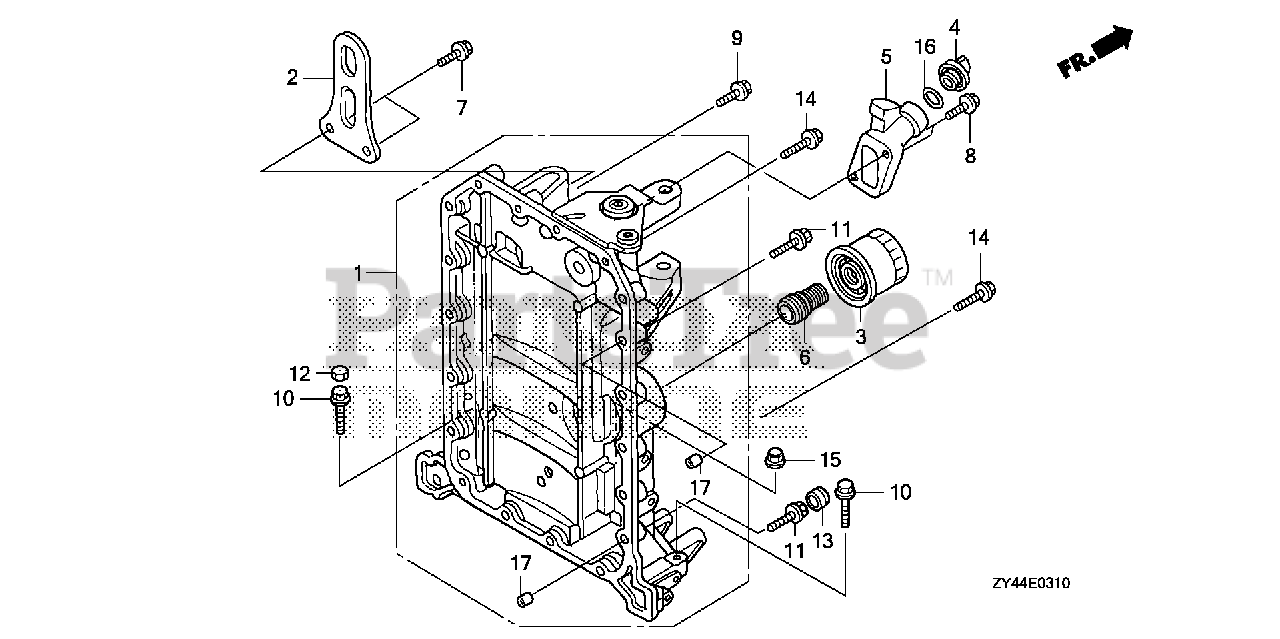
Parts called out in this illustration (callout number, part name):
1	CRANKCASE
2	HANGER, ENGINE
3	FILTER, OIL (FILTECH TOYO ROKI) (SOLD IN MULTIPLES OF 30)
3	FILTER, OIL (FILTECH TOYO ROKI) (SOLD INDIVIDUALLY)
4	CAP, OIL (YELLOW)
5	EXTENSION, OIL FILLER
6	HOLDER, OIL FILTER
7	BOLT, FLANGE (8X20)
8	BOLT, FLANGE (6X22)
9	BOLT, FLANGE (6X32)
10	BOLT, FLANGE (10X55)
11	BOLT, FLANGE (6X37)
12	CAP, BOLT (10MM)
13	CAP, BOLT (6MM)
14	BOLT, FLANGE (6X55)
15	NUT, FLANGE CAP (10MM)
16	O-RING (26X2.7)
17	PIN, DOWEL (8X14)
